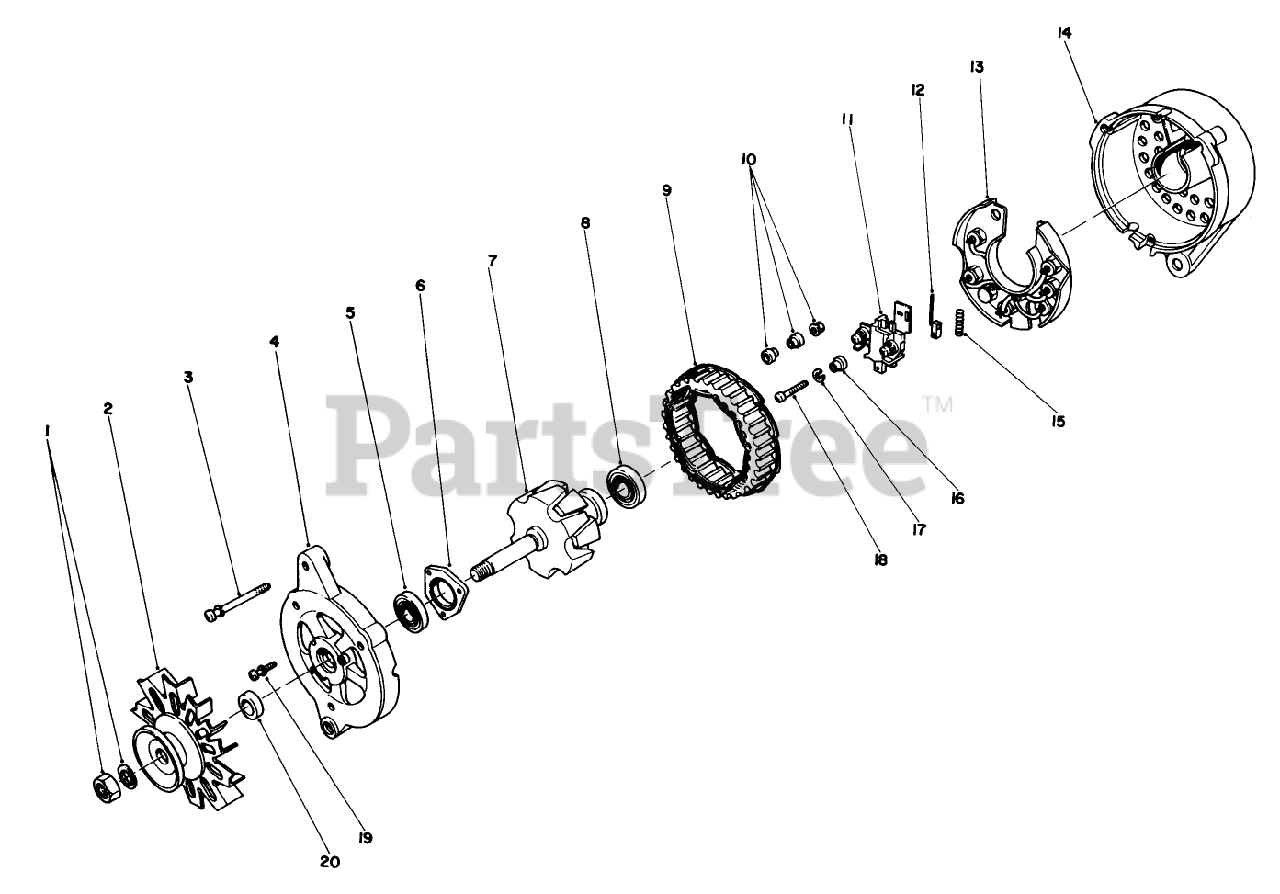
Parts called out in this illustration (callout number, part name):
1	NUT SET
2	Pulley Assembly (Incl. Ref. #20)
3	SCREW - SET
4	Bracket Assembly Front (Incl.Ref.#5-6 & 19)
5	Bearing-Front
6	Plate-Ball Bearing Retainer
7	Rotor Assembly (Incl. Ref. #8)
8	Bearing Rear
9	STATOR
11	Holder Assembly Brush (Incl. Ref. #12 & 15)
12	BRUSH
13	RECTIFIER
14	Bracket Assembly, Rear (Incl. Ref. #10-13 & 15-18)
15	BRUSH SPRNG
17	WASHER-LOCK, SPRING
18	SCREW MF 350769
19	Screw Set
20	Collar Shaft
